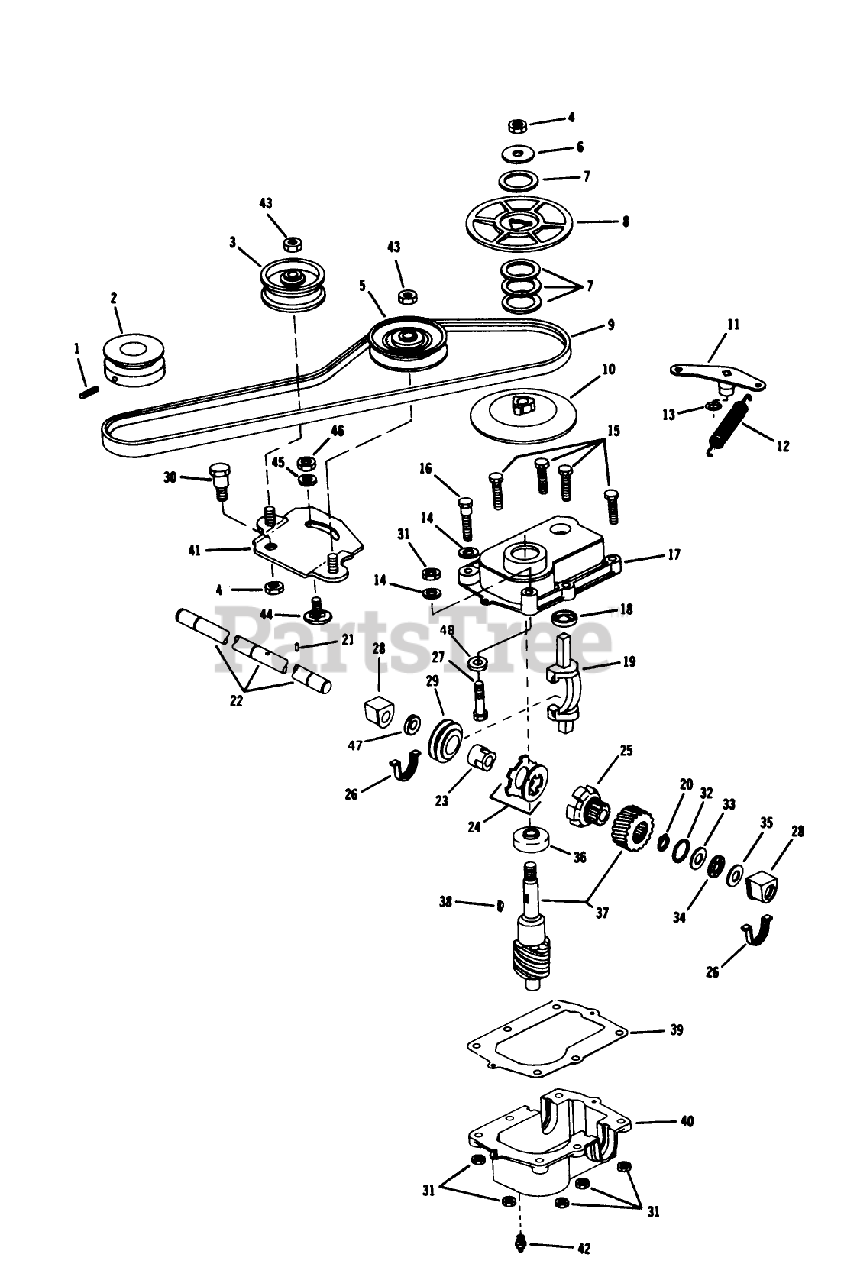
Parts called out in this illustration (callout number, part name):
1	SET SCREW F
2	PULLEY F
3	PULLEY NEWHAM IND *B
4	LOCKNUT
5	IDLER NEW HAM IND
6	WASHER
8	PULLEY UPPER PL
9	V-BELT
10	PULLEY LOWER PL
12	SPRING
13	O-RING
18	GUIDE ELCO
20	RET RING
21	PIN DRIVE LOCK
25	DRIVER BROCKWAY
28	BEARING & SEAL AY (12)
31	LOCKNUT E
33	WASHER-THRUST
35	THRUST WASHER
36	BEARING-BALL
38	KEY GALGER
39	GASKET HOOSIER
42	FITTING LINCOLN
43	NUT-JAM, LOCKING
45	WASHER M
46	NUT-LOCK F
47	WASHER
